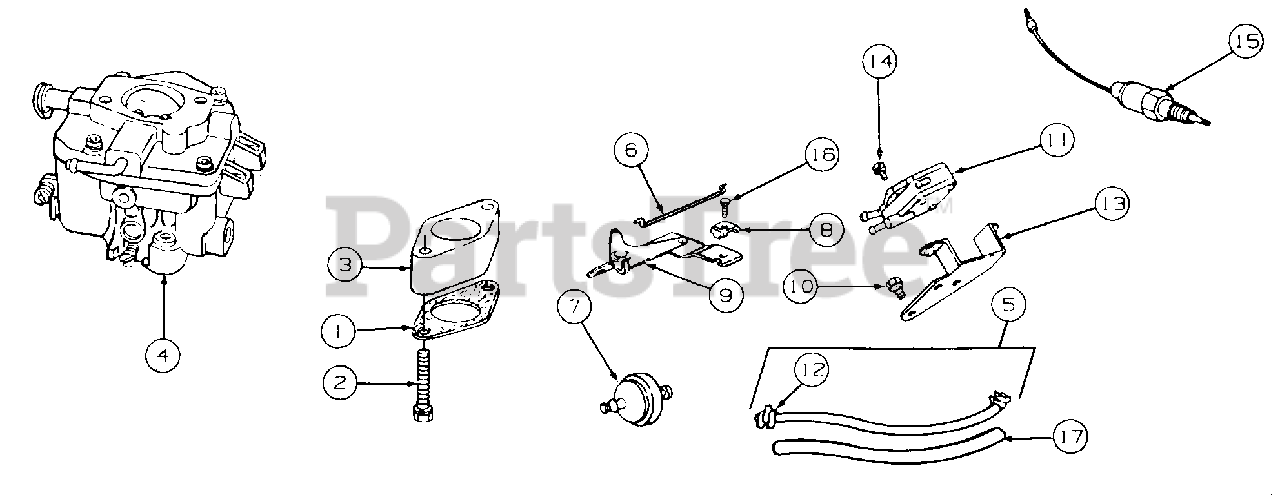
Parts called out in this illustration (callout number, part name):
1	Gasket, Carburetor Mtg
2	Screw, Sems
3	Spacer, Carburetor
4	Carburetor Assy
5	Line, Fuel
6	Link, Choke
7	Filter, Fuel
8	Clamp, Casing
9	Bracket, Choke
10	Screw, Sems
11	Pump, Fuel
12	Clamp, Fuel Line
13	Bracket, Fuel Pump
14	Screw, Mtg
15	Solenoid
16	Screw, Hex Hd
17	Insulation, Fuel Line
